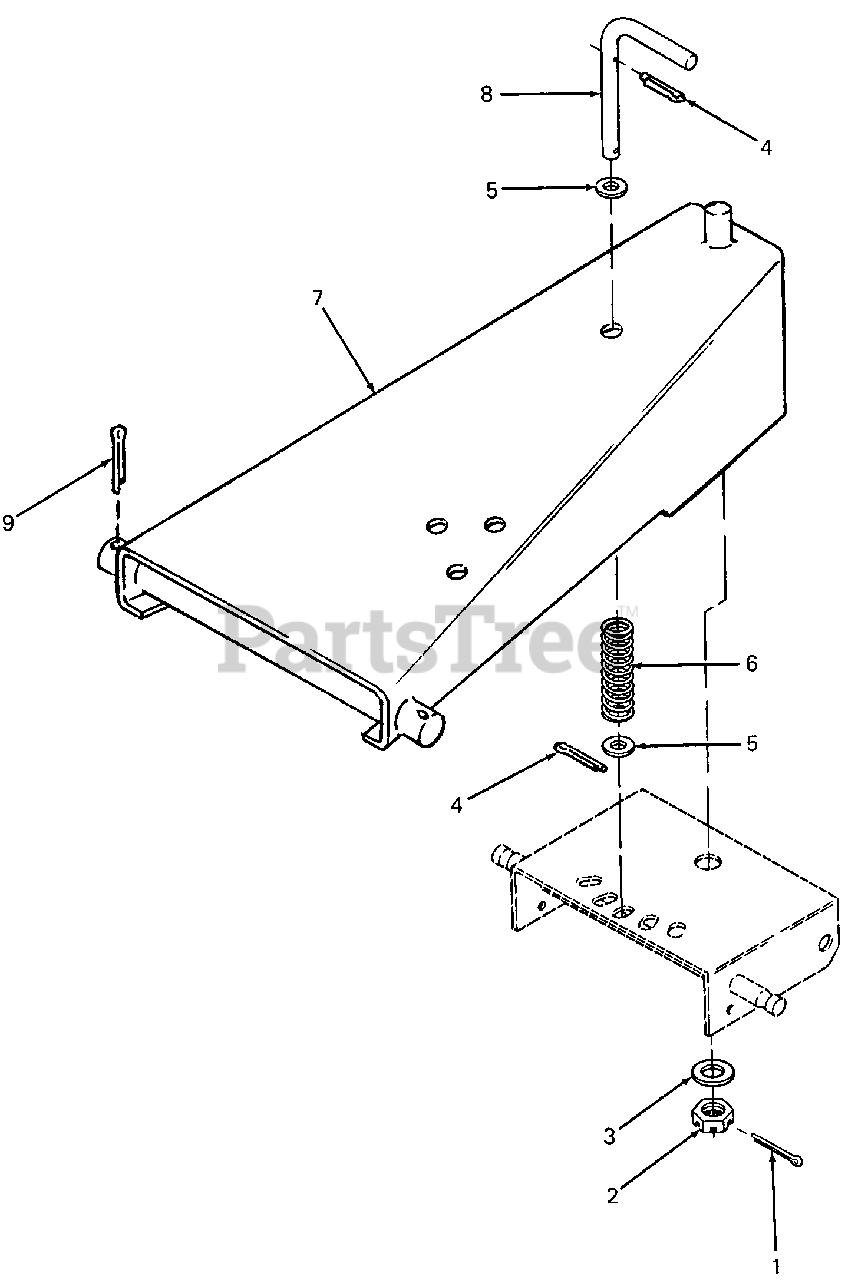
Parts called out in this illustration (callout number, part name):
1	Pin, Cotter, 1/8 Dia X 1-5/8 Lg
2	Nut, Hex Castle, 3/4-16 GR5
3	Washer, Flat, .812 X 1.47 X .108 Thk
4	Pin, Cotter, 5/32 Dia X 1.0 Lg
5	Washer, Flat, .510 X 1.0 X .060
6	Spring, Compression
9	Pin, Cotter, 5/32 Dia X 1-1/4 Lg
